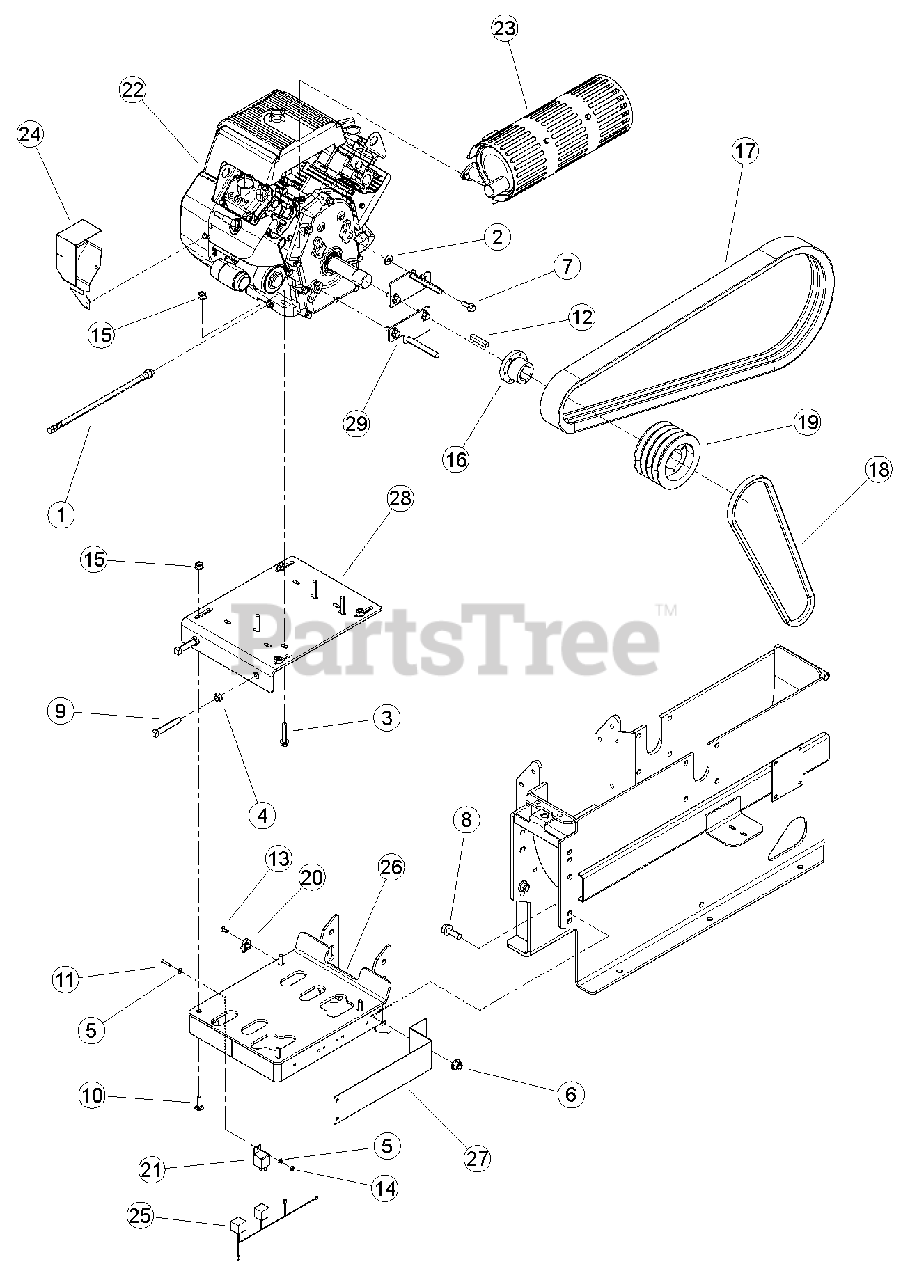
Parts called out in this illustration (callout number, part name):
1	HOSE ASSEMBLY, CRANKCASE DRAIN
2	WASHER, 3/8" FLAT ZP
3	BOLT, 3/8 X 2 FLANGE NC
4	NUT, 1/2 NC ZP JAM
5	WASHER, 3/16" FLAT ZP
6	NUT, 1/2-13 NYLOCK FLANGE
7	BOLT, 3/8 X 1 FLANGE NC
8	BOLT, 1/2-13 X 1-1/2 GR5 FLANGE NC
9	SETSCREW, 1/2 X 3 SQ HD 1/2 DOG PT
10	BOLT, 3/8 X 1-1/4" GR5 CRG NC ZP
11	SCREW, MCH 10-24 X 1" RND HD PHL ZP
12	KEY, 3/8" SQ X 2" LG PLAIN
13	RIVET, AL BLIND 1/4 X 3/4 DOME HEAD
14	NUT, #10-24 K-LOCK ZP
15	NUT, 3/8-16 NYLOCK FLANGE
16	BUSHING, SD 1-7/16"
17	BELT, 3B83 BANDED
18	BELT, BX44
19	SHEAVE, 4B5.2 SD
20	CLAMP, CABLE MOUNT
21	RELAY, 12V SPDT W/ FLANGE
22	ENGINE, SUBARU 720CC EH72 EFI (FOR SERVICE SEE ENGINE OWNER'S MANUAL OR YOUR NEAREST SUBARU INDUSTRIAL ENGINE DEALER)
23	MUFFLER, SUBARU STARTER SIDE (FOR SERVICE SEE ENGINE OWNER'S MANUAL OR YOUR NEAREST SUBARU INDUSTRIAL ENGINE DEALER)
24	CONTROL, SUBARU V-TWIN IGNITION/HOUR (FOR SERVICE SEE ENGINE OWNER'S MANUAL OR YOUR NEAREST SUBARU INDUSTRIAL ENGINE DEALER)
25	HARNESS, SAFETY RELAY
26	WELDMENT, ENGINE BASE
27	SHIELD, HYD PUMP
28	WELDMENT, ENGINE MOUNT PLATE
29	WELDMENT, BELT KICKER SUBARU
